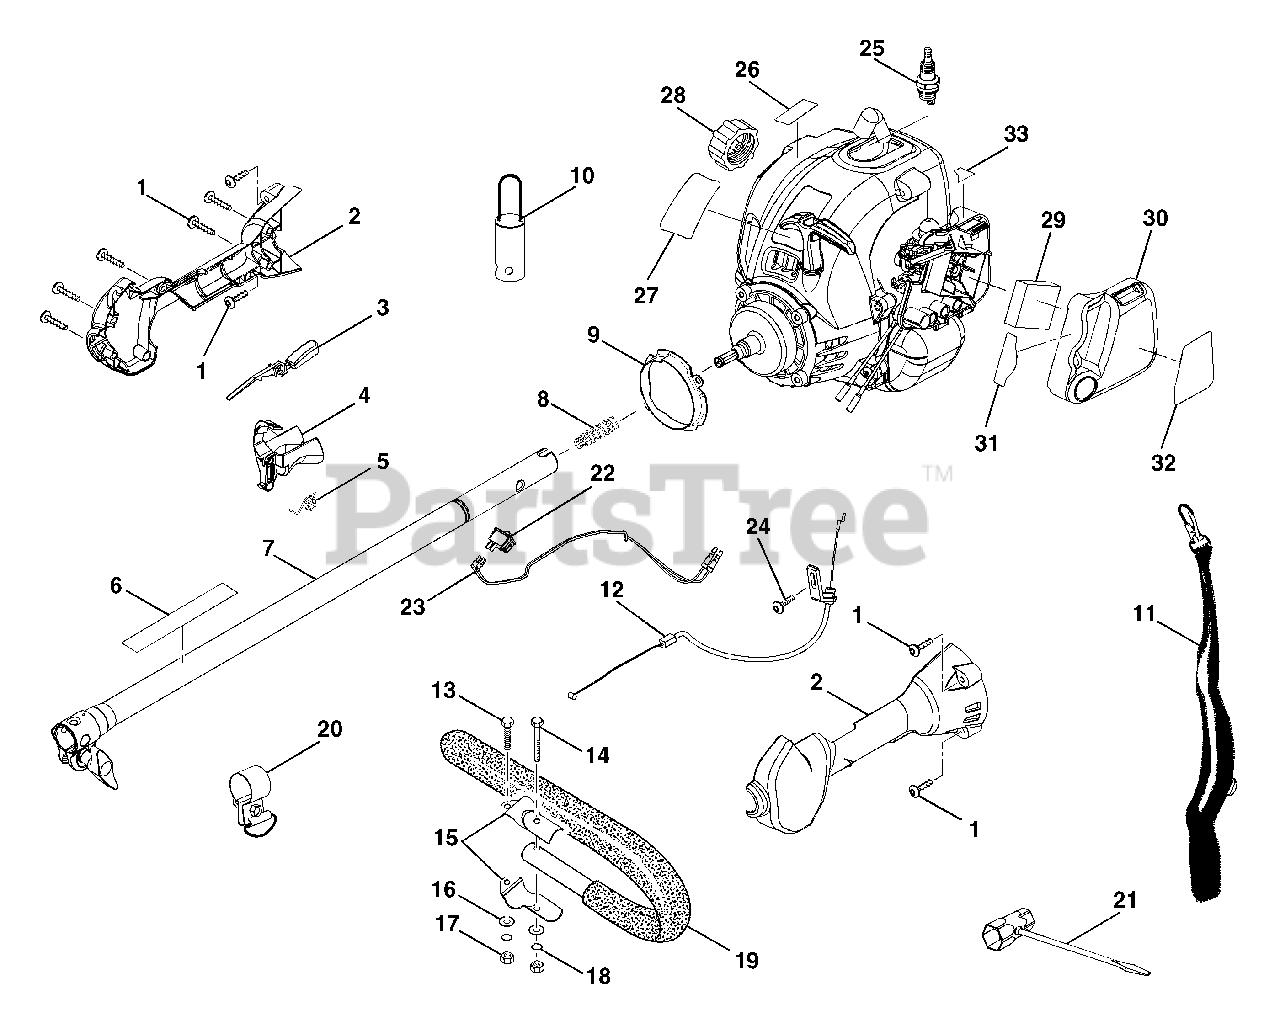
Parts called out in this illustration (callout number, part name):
1	SCREW (10-14 X 1 in. T. F. TRUSS HD.)
2	HANDLE ASSEMBLY
3	TRIGGER LOCK
5	TORSION SPRING
6	WARNING LABEL
7	BOOM ASSEMBLY
8	COMPRESSION SPRING
9	RING GUARD
10	STORAGE END CAP
11	SHOULDER STRAP
12	THROTTLE CABLE ASSEMBLY
13	BOLT (1/4-20 X 1 in. HEX HD.)
14	BOLT (1/4-20 X 1-1/2 in. HEX HD.)
15	HANDLE BAR CLAMP
16	WASHER
17	HEX NUT (1/4-20)
18	LOCK WASHER
19	J HANDLE AND GRIP
20	STRAP HANGER
21	COMBINATION WRENCH
22	SWITCH (MOMENTARY CONTACT)
23	LEAD ASSEMBLY
25	SPARK PLUG (CHAMPION RCJ6Y OR NGK BPM R7)
26	LOGO LABEL
27	MODEL LABEL
28	FUEL CAP ASSEMBLY
29	AIR FILTER
30	AIR BOX COVER
31	CHOKE DECAL
32	STARTING LABEL
33	PRIMER LABEL
